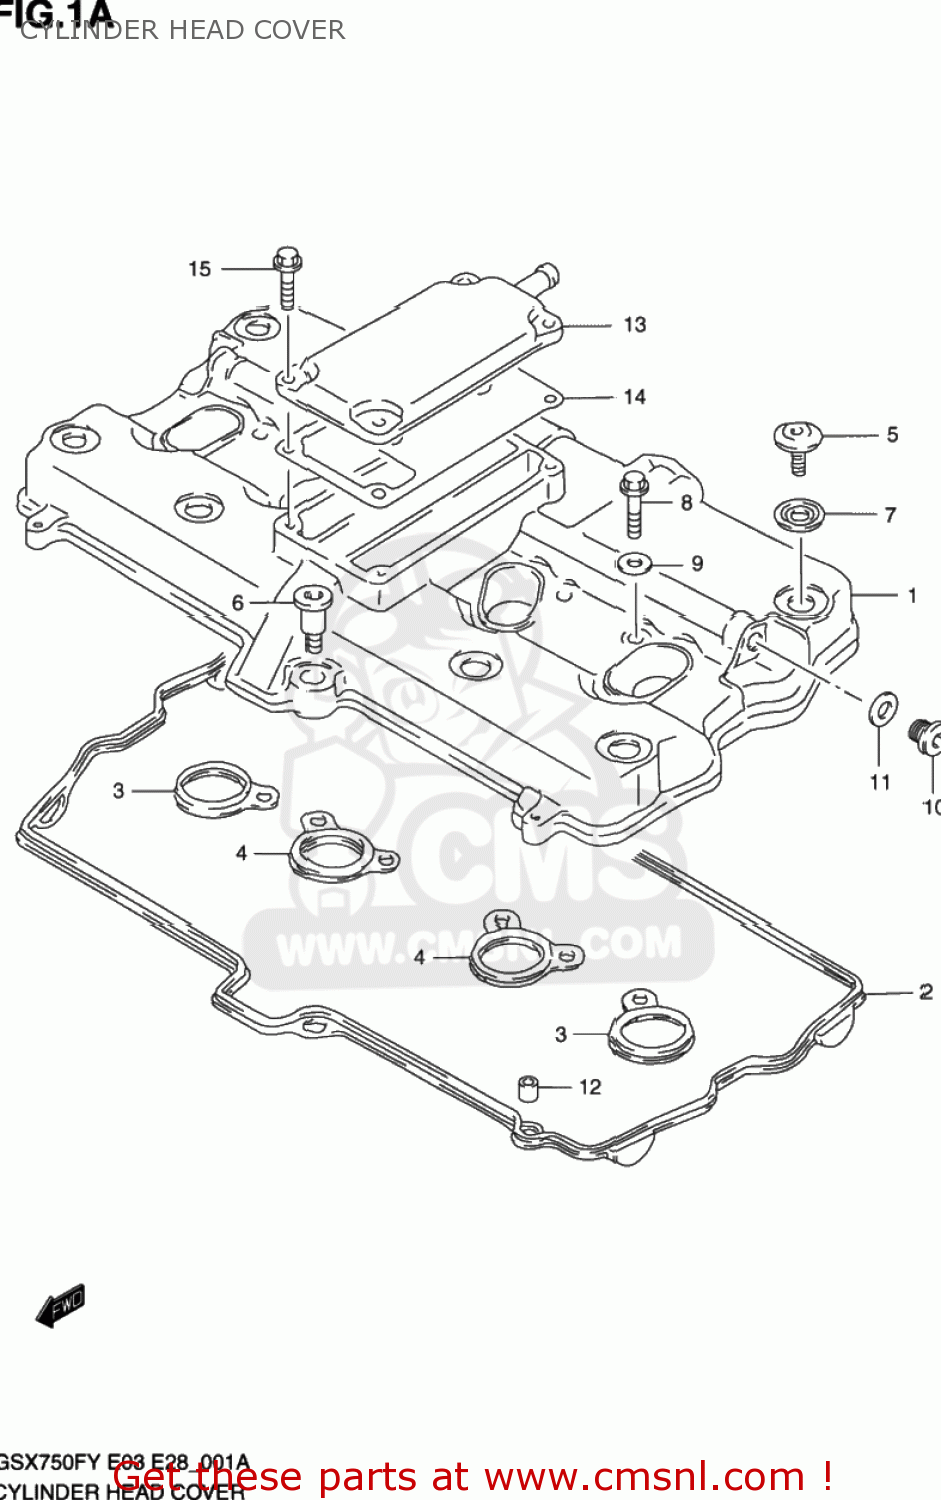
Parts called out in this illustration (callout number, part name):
1	COVER,CYLINDER HEAD
2	GASKET,CYLINDER HEAD COVER (NAS)
3	GASKET,HEAD COVER NO.2 (NAS)
4	GASKET,HEAD COVER NO.3 (NAS)
5	BOLT(7X17.5)
6	BOLT(7X31)
7	WASHER(10.6X25.5X2.3)
8	BOLT,UNION 8X35
9	GASKET 8.2X14X1 (NAS)
10	PLUG(L:12)
11	GASKET(12.1X16.2X3.7) (NAS)
12	PIN
13	COVER,BREATHER
14	GASKET,BREATHER COVER (NAS)
15	BOLT
